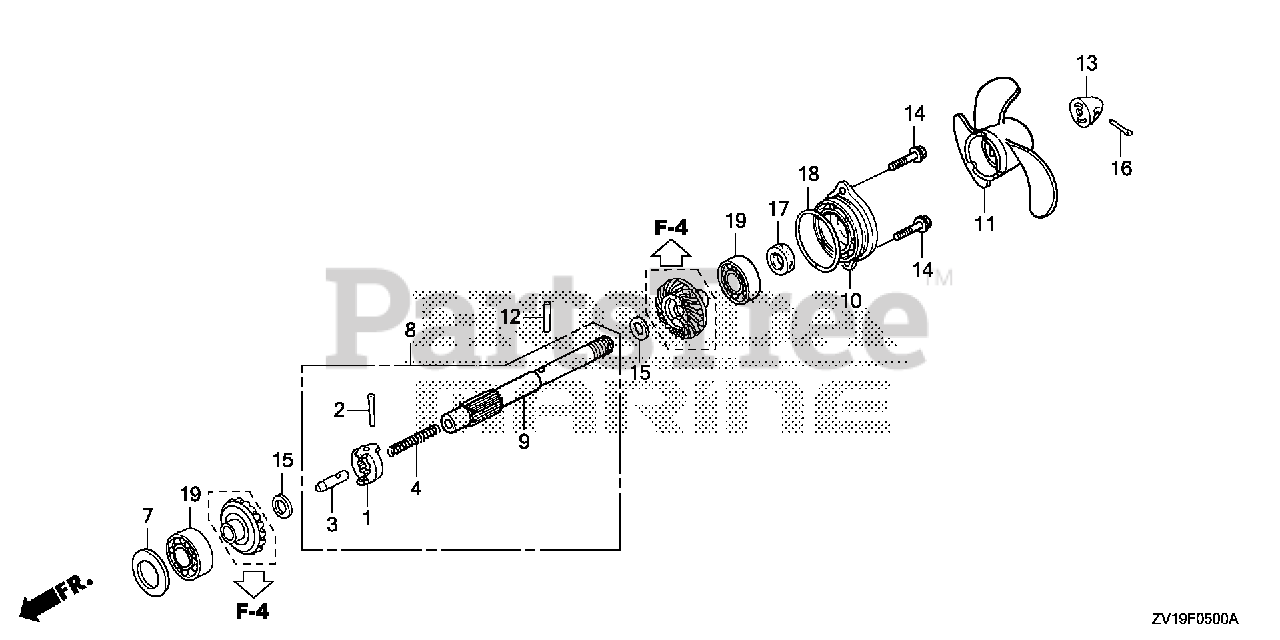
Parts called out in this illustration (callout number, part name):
1	SHIFTER, CLUTCH
2	PIN, SHIFTER (3X26)
3	SLIDER, SHIFT
4	SPRING, SHIFT
5	GEAR, BEVEL (F)
6	GEAR, BEVEL (R)
7	SHIM B, GEAR (0.10MM)
8	SHAFT, PROPELLER
9	SHAFT, PROPELLER
10	HOLDER, PROPELLER SHAFT *NHB14M* (AQUA MARINE SILVER METALLIC)
11	PROPELLER, THREE-BLADE (7-7/8X7-1/2) *NH283* (STIN GRAY)
11	PROPELLER, THREE-BLADE (200X170) *NH283* (STIN GRAY)
12	PIN, SHEAR
13	CAP, PROPELLER
14	BOLT, FLANGE (6X16) (SUS)
15	WASHER (13MM)
16	PIN, COTTER
17	SEAL, WATER (13MM) (ARAI)
18	O-RING (52MM)
19	BEARING, RADIAL BALL (6004)
